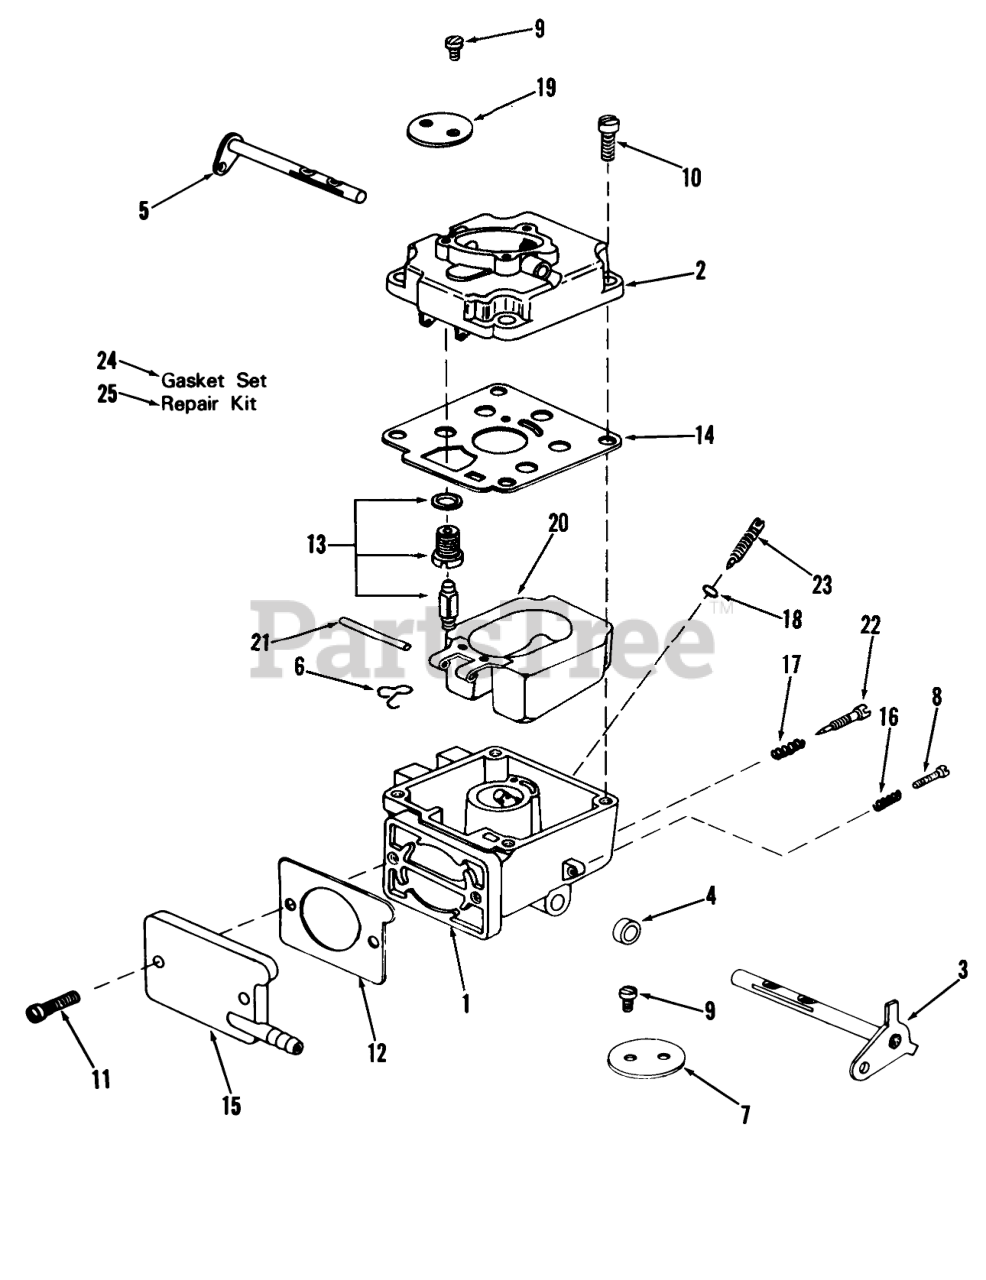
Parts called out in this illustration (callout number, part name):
3	Shaft-Throttle
5	SHAFT-CHOKE
9	Screw-Fly Mounting
10	SCREW-BOWL COVER MTG
11	SCREW-BOWL COVER MTG
14	? Gasket
21	Shaft,Float Lever
